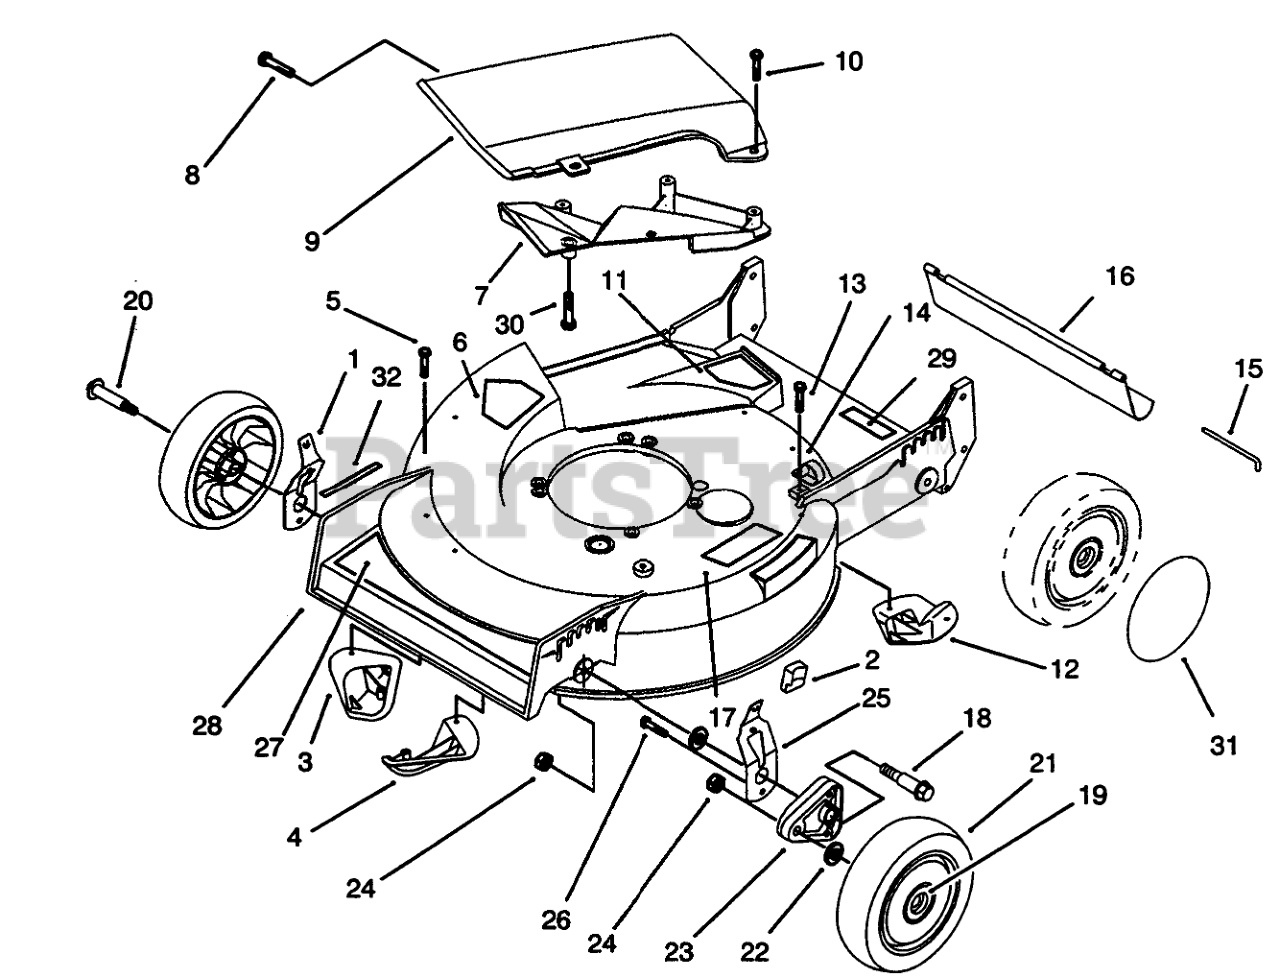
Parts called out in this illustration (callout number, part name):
1	RH SPRING ARM ASM
2	KNOB-ARM
3	KICKER-FRONT
4	KICKER-RH
5	Screw-Pan Hd.
6	DECAL-DANGER
7	Deflector-Recycler
8	SCREW AND WASHER ASM
9	Cover Assembly Incl. Ref. #7 & 30)
10	SCREW-HWH
11	DECAL - DANGER
12	KICKER-REAR
13	SCREW-HWHTF
14	CLAMP-R
15	ROD-SHIELD
16	SHIELD-TRAILING
17	DECAL - DANGER
18	BOLT-SHOULDER
19	BUSHING
20	BOLT-WHEEL
21	Wheel & Tire Assembly (Incl. Ref. #19)
22	WASHER
23	ARM-PIVOT, FRONT
24	NUT-LOCK
25	LH SPRING ARM ASM
26	SCREW-HWH
27	DECAL - DECK
28	Housing Assembly (Incl. Ref. #3-6, 11, 12, 17, 29, & 32)
29	DECAL - WARNING
30	Screw-Pan Hd.
31	WHEEL COVER
32	DECAL - HOC
